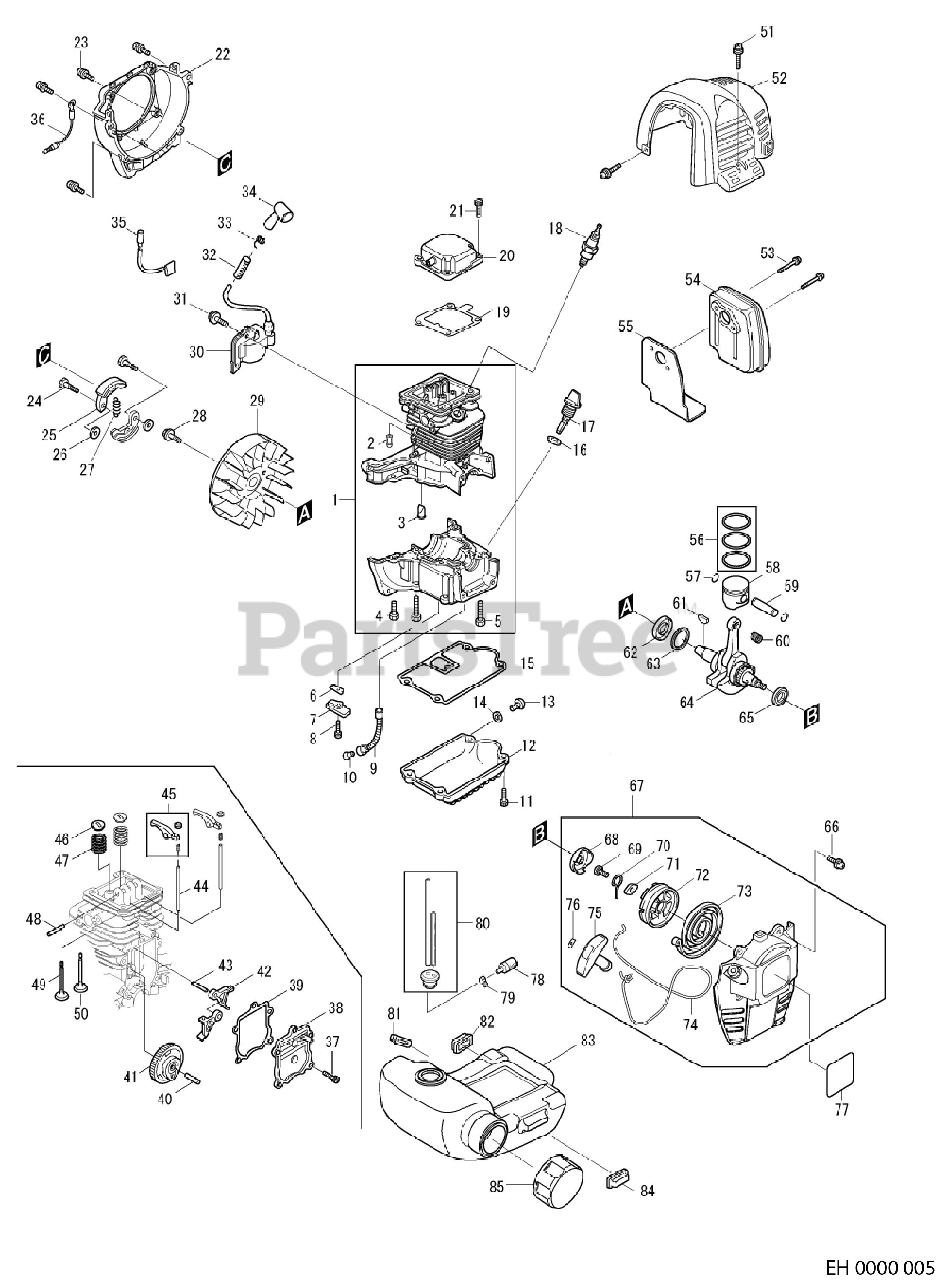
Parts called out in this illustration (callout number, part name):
1	CYLINDER BLOCK SET
2	SPACER
3	VALVE, CHECK
4	BOLT - M5X16
5	BOLT - M5X33
6	LEAD VALVE
7	RETAINER PLATE
8	BOLT - M4X10
10	WEIGHT
11	BOLT - M5X14
14	GASKET
16	GASKET
18	PLUG, SPARK -CMR6A
19	GASKET, ROCKER COVER
21	BOLT - M5X14
22	HOUSING, BLOWER
23	BOLT - M5X16
24	BOLT - M8X24
25	SHOE, CLUTCH
27	SPRING, CLUTCH
28	BOLT - M6X16
30	COIL, IGNITION
31	BOLT - M4X20
32	TUBE
33	TERMINAL, SPARK PLUG CAP
35	LEAD UNIT
36	WIRE
37	BOLT - M5X14
38	COVER, CAM GEAR
39	GASKET, COVER CAM GEAR
40	PIN - 5X21.8
43	PIN - 4×15.8
45	ROCKER ARM ASSY
46	RETAINER, SPRING
47	SPRING - 13
48	PIN - 5×31.8
49	VALVE, EXHAUST
50	VALVE, INTAKE
51	SCREW - M5X12
52	COVER, CYLINDER
53	BOLT - M5X40
54	MUFFLER
55	GASKET, EXHAUST
56	PISTON RING SET
59	PIN, PISTON
60	NEEDLE CAGE1014
61	KEY - 3
62	SEAL, OIL - 12
63	WASHER - 26
64	CRANKSHAFT CP
65	SEAL, OIL - 12
66	SCREW - M5X14
67	COVER STARTER ASSY
69	SCREW - 5X12 (TAPPING)
70	ARM, SWING
74	ROPE, STARTER
75	KNOB, STARTER
76	STOPPER, ROPE
78	FILTER, FUEL
79	CLAMP, HOSE
83	TANK, FUEL
85	CAP, FUEL TANK
